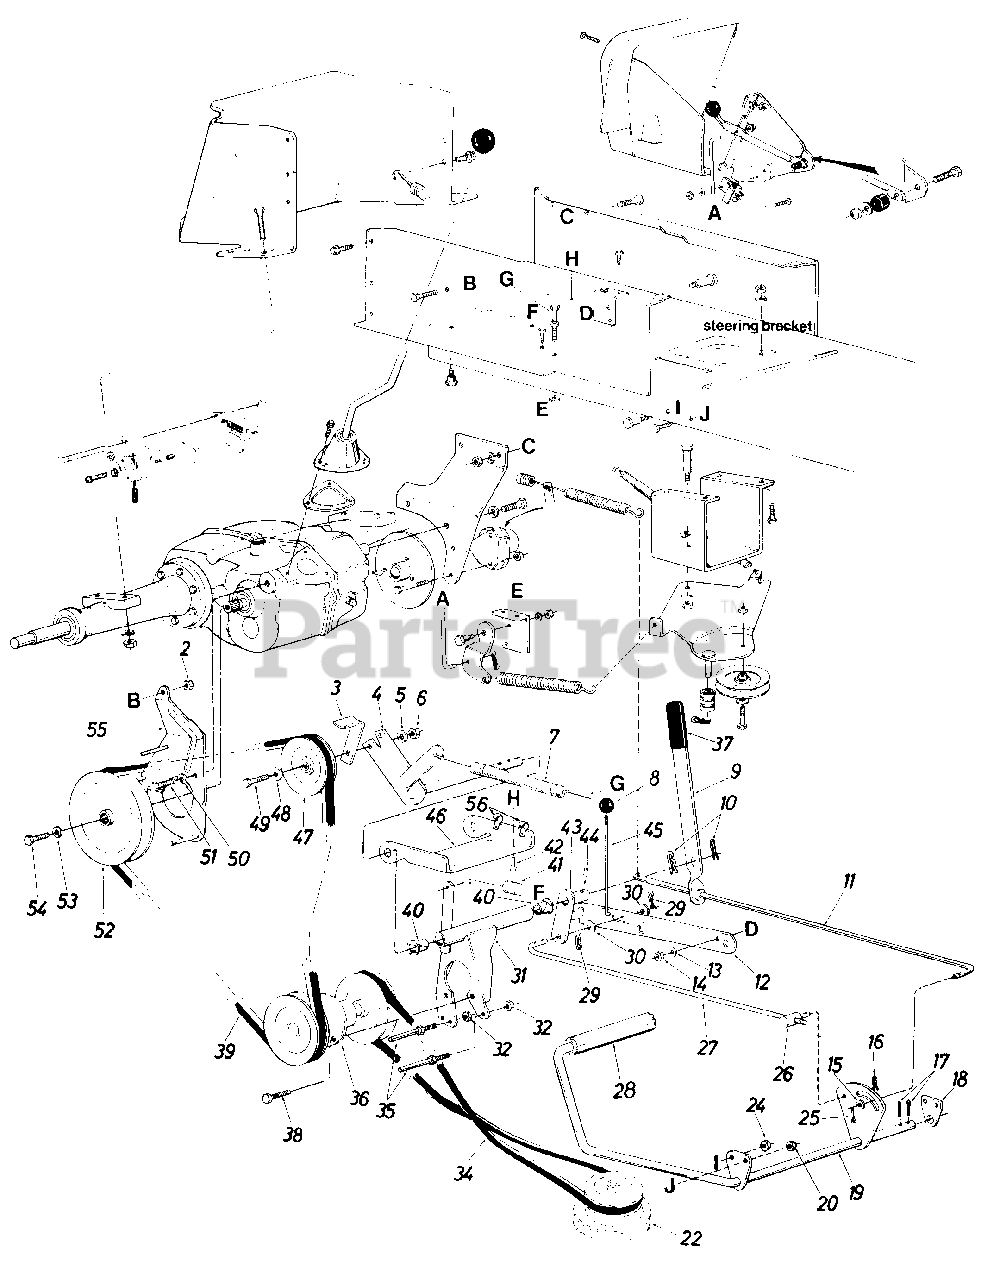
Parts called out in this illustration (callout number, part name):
2	Hex L-Nut 3/8-16 Thd.
5	L-Wash. 3/8" Scr.
6	Hex Nut 3/8-16 Thd.
7	Ext. Spring
8	Knob
9	Hand Brake Lever
10	Hairpin Cotter 3/8" Rod
11	Brake Rod
12	Parking Brake Cam
13	Fl-Wash. 5/16" Scr.
14	Hex Nut 5/16-18 Thd.
15	Fl-Wash. 5/16" Scr.
16	Hairpin Cotter 3/8" Rod
17	Cotter Pin 1/8" Dia. x 1.00" Lg.*
18	Clutch Rod Brg. Brkt.
19	Clutch-Brake Pedal Ass'y.
20	Hex Cent. L-Nut 3/8-16 Thd.
22	Engine Pulley 4.75 & 5.56
24	Hex Cent. L-Nut 3/8-16 Thd.
25	Cotter Pin 3/32" Dia. x .75" Lg.*
26	Pivot Bushing
27	Brake Cam Rod
28	Foot Pad
29	Hairpin Cotter 3/8" Rod
30	Fl-Wash. 3/8" I.D. x 1.00" O.D. x .030
31	Jack Shaft Mtg. Brkt. Ass'y.
32	Hex Top L-Nut 3/8-16 Thd.
34	"V"-Belt 1/2 x 59" Lg. (Polyester)
35	Stud 3/8-16 x 3.62" Lg. Special
36	Jack Shaft Ass'y.
37	Flat Grip
38	Hex Sem Scr. 5/16-18 x .75" Lg.
39	"V"-Belt 1/2 x 40" Lg. [ (Kevlar)
40	Nyliner 5/8" I.D. x .88" Lg.
41	Ext. Spring
42	Hex Thd. Rolling Scr. 1/4-20 x .50" Lg.
43	Clutch-Idler Horn Ass'y.
44	Spring Pin Spiral 1/4" Dia. x 1.00" Lg.
45	Parking Brake Link
46	Idler Mtg. Brkt.-Drive
47	4" "V"-Idler Pulley
48	Fl-Wash. 3/8" I.D.
49	Hex Scr. 3/8-16 x 1.75" Lg.
50	L-Wash. 3/8" Scr.*
51	Hex Scr. 3/8-16 x .75" Lg.
52	"V"-Pulley 7.0" O.D.
53	L-Wash. 3/8" I.D.*
54	Hex Scr. 3/8-24 x .75" Lg.
55	Belt Guard Ass'y.
56	Plastic Hose Clamp
